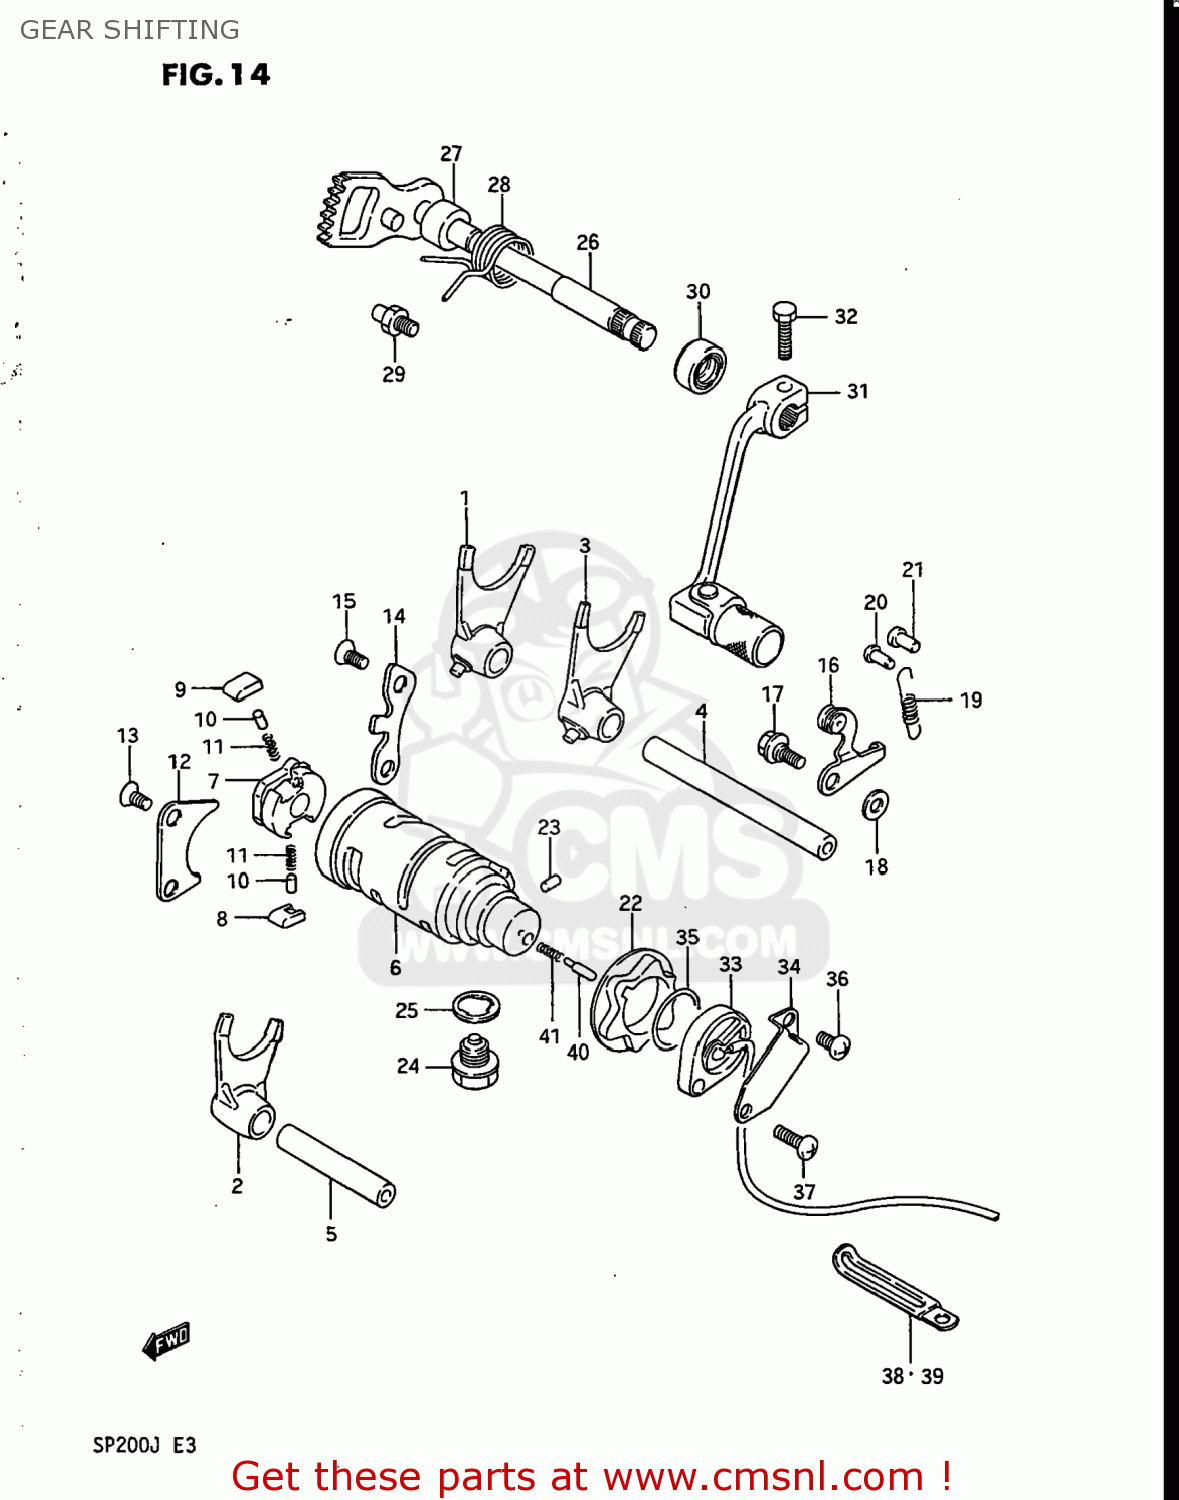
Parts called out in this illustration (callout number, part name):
1	FORK,GEAR SHIFT NO.1
2	FORK,GEAR SHIFT NO.2
3	FORK,GEAR SHIFT NO.3
4	SHAFT,GEAR SHIFT FORK(L:109)
5	SHAFT,GEAR SHIFT FORK
6	CAM,GEAR SHIFT
7	GEAR,GEARSHIFT CAM DRIVE
8	PAWL,GEAR SHIFT NO.1
9	PAWL,GEAR SHIFT NO.2
10	PIN(5X8)
11	SPRING
12	LIFTER,GEAR SHIFT POLE
13	SCREW
14	GUIDE,GEAR SHIFT CAM
15	SCREW
16	STOPPER COMP,GEAR SHIFT
17	BOLT
18	WASHER
19	SPRING
20	RIVET
21	RIVET
22	PLATE,GEAR SHIFT CAM STOPPER
23	PIN 4X6
24	PLUG (14X12)
25	GASKET(14X19.2X2) (NAS)
26	SHAFT,GEAR SHIFT
27	SPACER(12X20X15.3)
28	SPRING
29	STOPPER,GEAR SHIFT CAM
30	OIL SEAL
31	LEVER ASSEMBLY,GEAR SHIFTING
32	BOLT
33	BASE ASSEMBLY,GEAR SHIFT TERMINAL
34	PROTECTOR,GEAR SHIFT SW
35	O-RING (D:2.4 ID:22.2)
36	SCREW
37	SCREW
38	CLAMP
39	CLAMP
40	PIN(5X15.5)
41	SPRING
